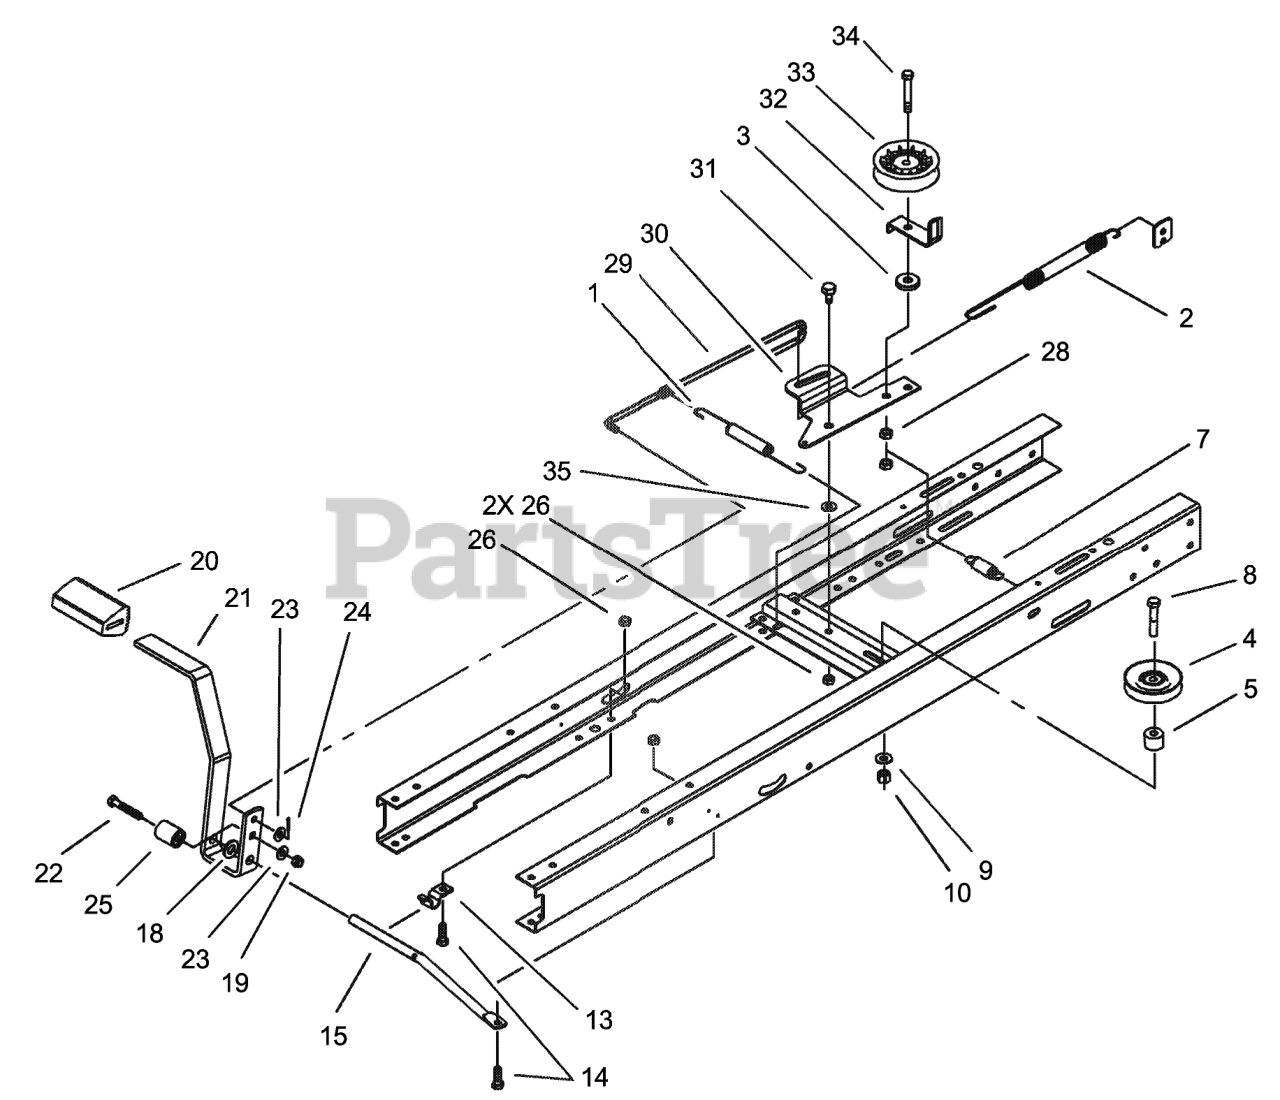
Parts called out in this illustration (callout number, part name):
1	SPRING-EXTENSION
2	SPRING-EXTENSION
3	WASHER
4	PULLEY-IDLER
5	SPACER
7	SPRING-EXTENSION
8	SCREW-HH
9	WASHER-FLAT
10	NUT-LOCK, NI
13	CLAMP-PIVOT, SHIFT
14	SCREW-HH
15	ROD-PIVOT, PEDAL
18	WASHER-FLAT
19	NUT-LOCK, NI
20	PAD-PEDAL
21	PEDAL-CLUTCH/BRAKE, HYDRO
22	SCREW-HH
23	WASHER-PLAIN
24	PIN-COTTER
25	SPACER
26	NUT-LOCK, NI
28	NUT-LOCK, NI
29	ROD-CLUTCH/BRAKE
30	ARM-IDLER
31	BOLT-SHOULDER
32	GUIDE-IDLER, BELT
33	PULLEY-IDLER
34	SCREW-HH
35	WASHER-PIVOT
